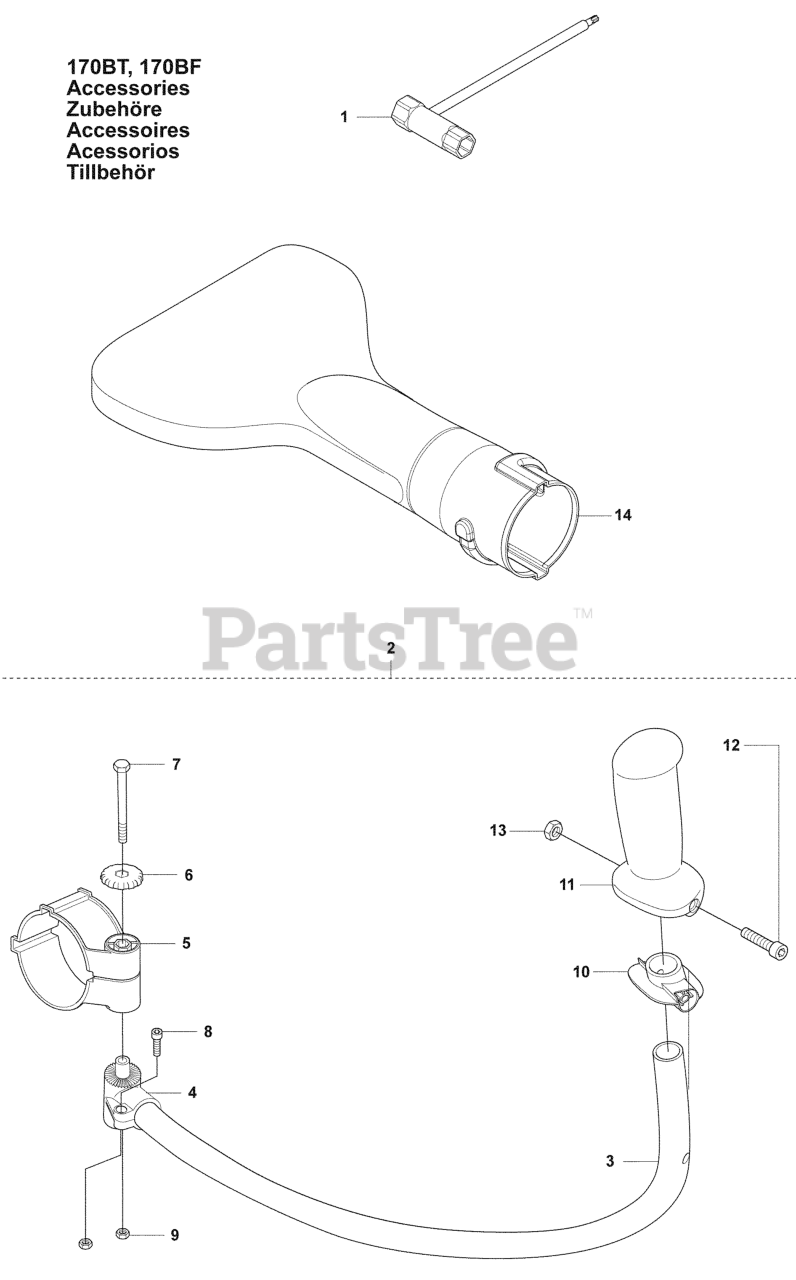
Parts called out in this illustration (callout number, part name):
1	SOCKET
2	HANDLE 170 BT
5	HOLDER TH
8	SCREW MC6S 5X10
14	FLAT NOZZLE
